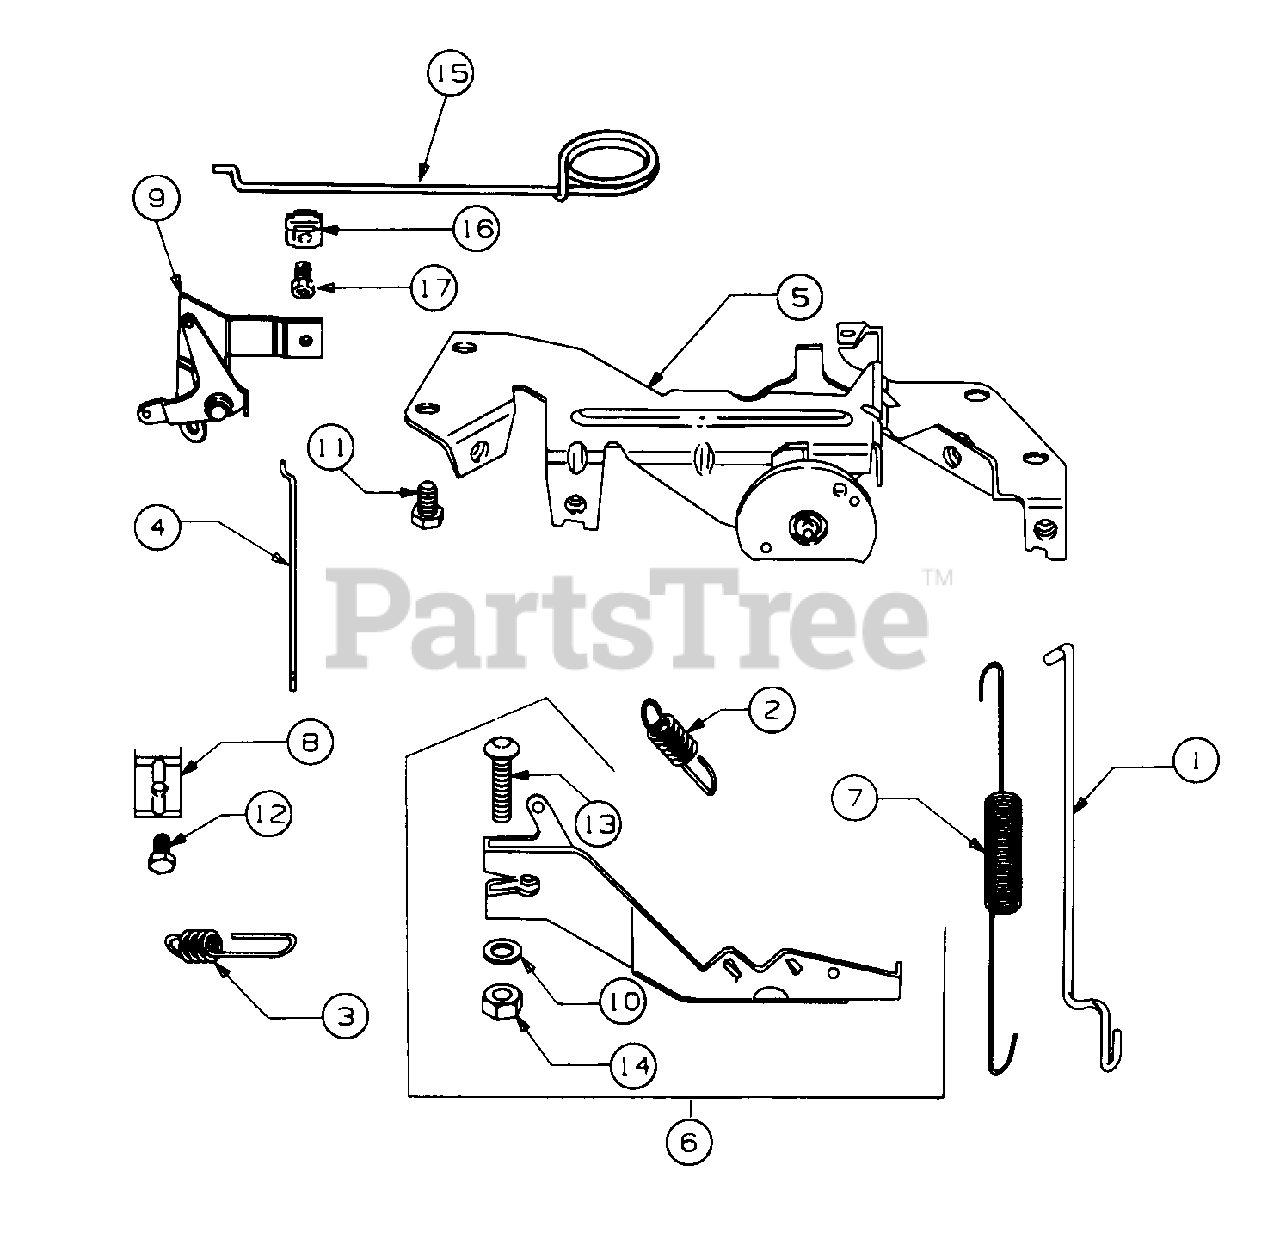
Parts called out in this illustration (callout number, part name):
1	Link, Governor
2	Spring, Governor
3	Spring, Governed Idle
4	Link, Choke
5	Bracket, Governor Control
6	LeverAssy, Governor
7	Spring, Governor Link
8	Clamp, Casing
9	Bracket, Choke Control
11	Screw, Sem
12	Screw, Hex Head
14	Nut, Hex
15	Rod, Manual Choke
16	Clip, Friction
17	Screw, Sem
